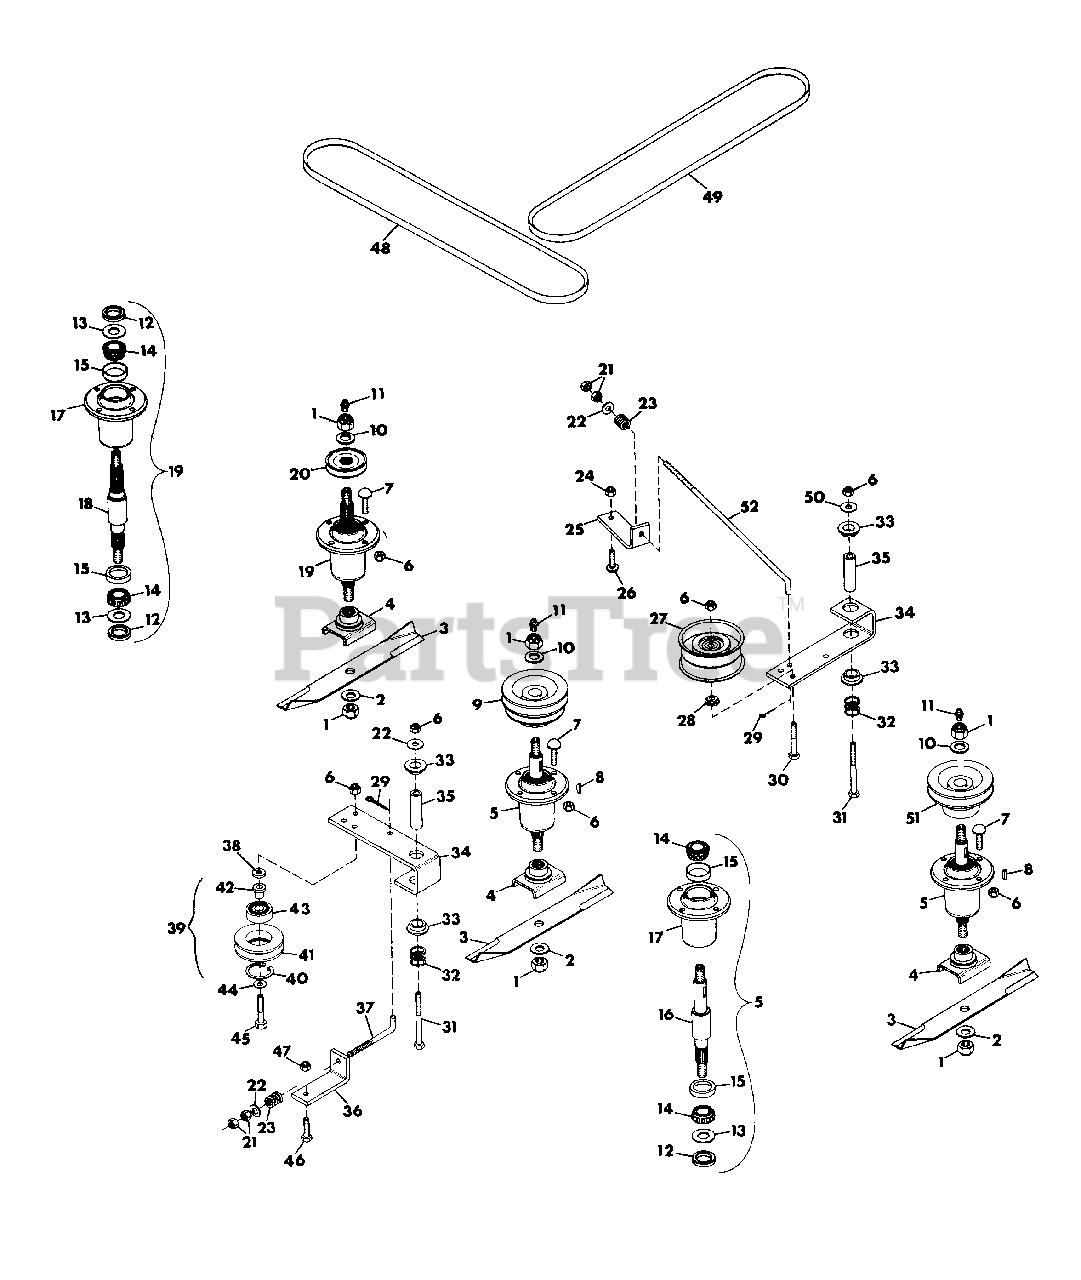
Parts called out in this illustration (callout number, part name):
1	NUT, LOCK 5/8-11
2	WASHER, FLAT .656X1.312X.095
3	BLADE
4	WELDMENT, BLADE CRADLE
5	ASSEMBLY, SPINDLE
6	NUT, LOCK 3/8-16
7	BOLT, 3/8-16X1.25 RD HD SQ NK
8	KEY, WOODRUFF .250X1 HARD
9	SHEAVE, SPINDLE
10	WASHER, FLAT .687X1.312X.122
11	FITTING, LUBE 1/8 NPT
12	SEAL, STEEL(IN 34605)
12	SEAL, STEEL(IN 21306)
13	WASHER, FLAT .975X1.970X.030(IN 34605)
13	WASHER, FLAT .975X1.970X.030(IN 21306)
14	BEARING, CONE
15	BEARING, CUP
16	SHAFT, SPINDLE
17	HOUSING, BEARING
18	SHAFT, SPINDLE
19	ASSEMBLY, SPINDLE
20	SHEAVE, SPINDLE
21	NUT, HEX 3/8-16
22	WASHER, FLAT .406X.812X.065
23	SPRING, COMP. 1X.78
24	NUT, LOCK 5/16-18
25	BRACKET, BELT TENSIONER
26	BOLT, 5/16-18X1.00 RD HD SQ NK
27	PULLEY, IDLER
28	BUSHING, REAR FENDER
29	PIN, COTTER .094X.75
30	BOLT, HEX 3/8-16X2.25
31	BOLT, HEX 3/8-16X3.25
32	SPRING, COMP. 1X.80
33	BUSHING, NYLON .76X1X.6
34	ARM, IDLER PIVOT
35	SPACER
36	BRACKET, BELT TENSIONER
37	ROD, IDLER
38	SPACER, IDLER .406X.750X.188
39	ASSEMBLY, IDLER SHEAVE
40	RING, RETAINING
41	SHEAVE, IDLER
42	BUSHING, IDLER SHEAVE
43	BEARING, BALL
44	WASHER, FLAT .375X1.125X.065
45	BOLT, HEX 3/8-16X2.00
46	BOLT, HEX 1/2-13X1.50
47	NUT, LOCK 1/2-13
48	BELT, MOWER A44
49	BELT, PRO-50 MOWER
50	WASHER, FLAT .438X1.000X.083
51	SHEAVE, SPINDLE
52	ROD, IDLER
